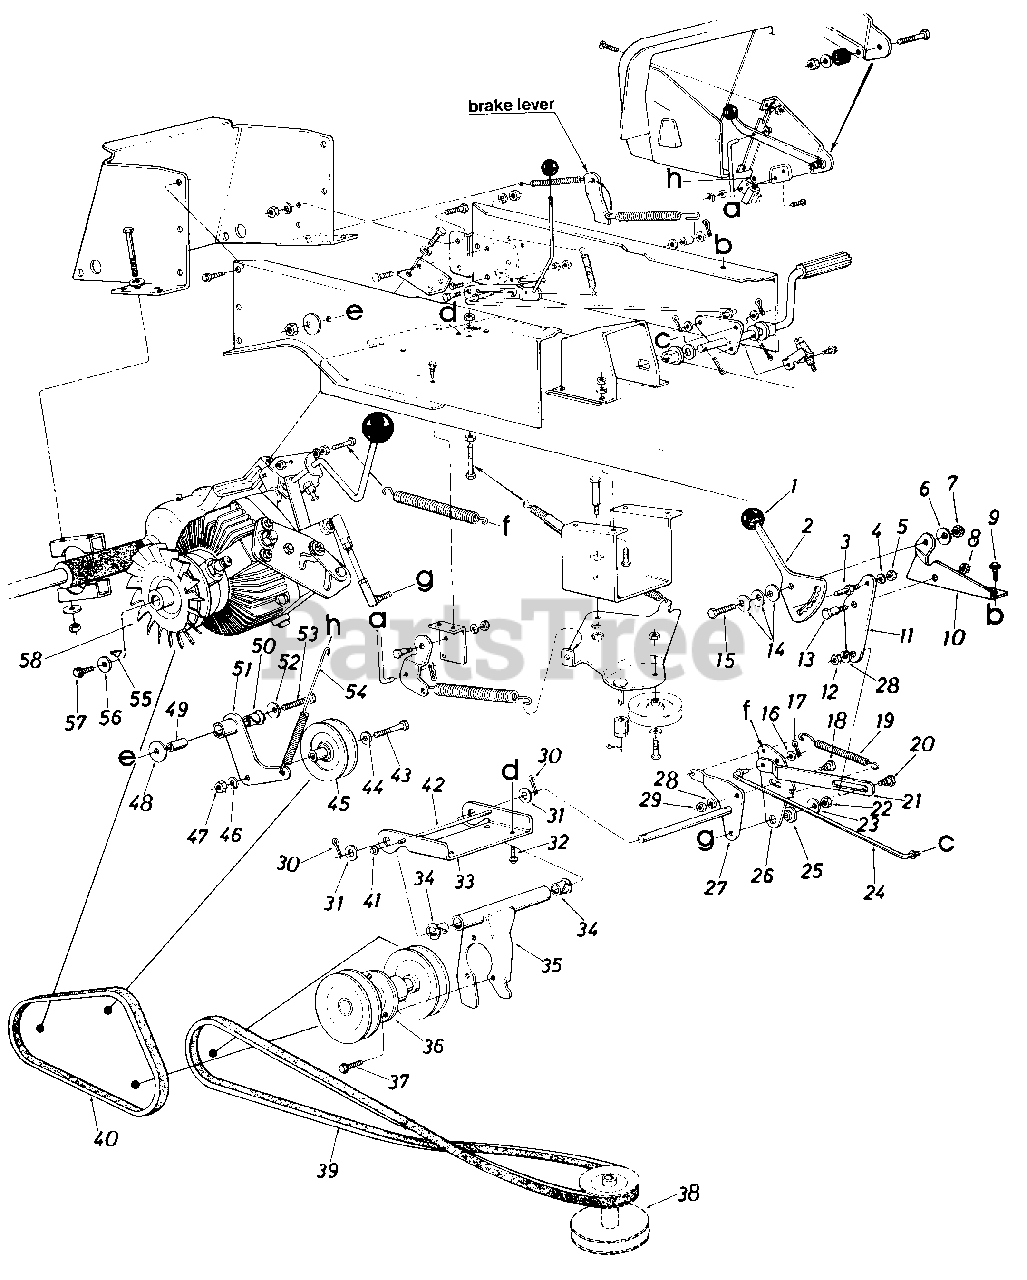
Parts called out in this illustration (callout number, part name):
1	"T" Shift Knob
2	Speed Selector Cam
3	Hex Stud .250" Dia. x .62"
4	L-Wash. 1/4" I.D.
5	Hex Nut 1/4-20 Thd.
6	Bell-Wash. .400" I.D. x 1.13' O.D.
7	Hex Ins. L-Nut 3/8-24 Thd.
8	Hex Top L-Nut 3/8-16 Thd.
9	Hex Wash. Hd. S-Tap Scr. 1/4-20 x .75" Lg.
10	Speed Selector Mtg. Brk't.
11	Speed Selector Transfer Brk't.
12	Hex Nut 5/16-18 Thd.
13	Shld. Bolt .500" Dia. x .170
14	Bell-Wash. .39" I.D. x 1.13" O.D.
15	Hex Bolt 3/8-24 x 1.00" Lg.
16	Fl-Wash. .385" I.D. x .87" O.D.
17	Cotter Pin 3132" Dia. x .75" Lg.
18	Shld. Bolt .437" Dia. x .180
19	Extension Spring .50" Dia. x 2.75" Lg.
20	Shld. Bolt .437" Dia. x .180
21	Speed Selector Link
22	Hex Top L-Nut 3/8-24 Thd.
23	Bell-Wash. .39" I.D. x 1.13" O.D.
24	Rod Speed Control .312" Dia.
25	Shld. Spacer.625" I.D.
26	Speed Cont. Transfer Swivel Brk't.
27	Speed Control Transfer Ass'y.
28	L-Wash. 5/16" I.D.
29	Hex Nut 5/16-18 Thd.
30	Cotter Pin 118" Dia. x 1.00" Lg.
31	Fl-Wash. .69" I.D> x 1.24" O.D.
32	Hex Wash S-Tap Scr. 1/4-20 x .50" Lg.
33	Idler Mtg. Brk't.
34	Flanged Nyliner Brg. .376 I.D. x .437
35	Mounting Brk't. Ass'y.
36	Jack Shaft Ass'y.
37	Hex Sems Bolt 5/16-18 x .75" Lg.
38	Engine Pulley 47.5" I.D. x 5.56" O.D.
39	"V"-Belt 1/2" x 59.0" Lg.
40	"V"-Belt 1/2" x 32.0" Lg.
41	Push Cap
42	Rod 3/16" Dia. x 7.12" Lg.
43	Hex Bolt 3/8-24 x 1.50" Lg.
44	Fl-Wash. .385" I.D. x .87" O.D.
45	Idler Pulley 4.0" O.D. x 5/8"-"V"
46	L-Wash. 3/8 I.D.
47	Hex Nut 3/8-24 Thd.
48	Bell-Wash. .40" I.D. x .87" O.D.
49	Spacer.38" I.D. x .62" O.D. x 1.87" Lg.
50	Flanged Nyliner Brg.
51	Idler Pivot Brk't. Ass'y.
52	Fl-Wash. .385" I.D> x .87" O.D.
53	Hex Bolt 3/8-24 x 2.00" Lg.
54	Extension Spring .56" O.D. x 7.75" Lg.
55	#9 Hi-Pro Key .316" x .75"
56	Fl-Wash. .25" I.D. x .938" O.D.
57	Hex Wash. Hd. TT-Tap Scr. 1/4 x .75" Lg.
58	Trans. Pulley and Fan Assy.
